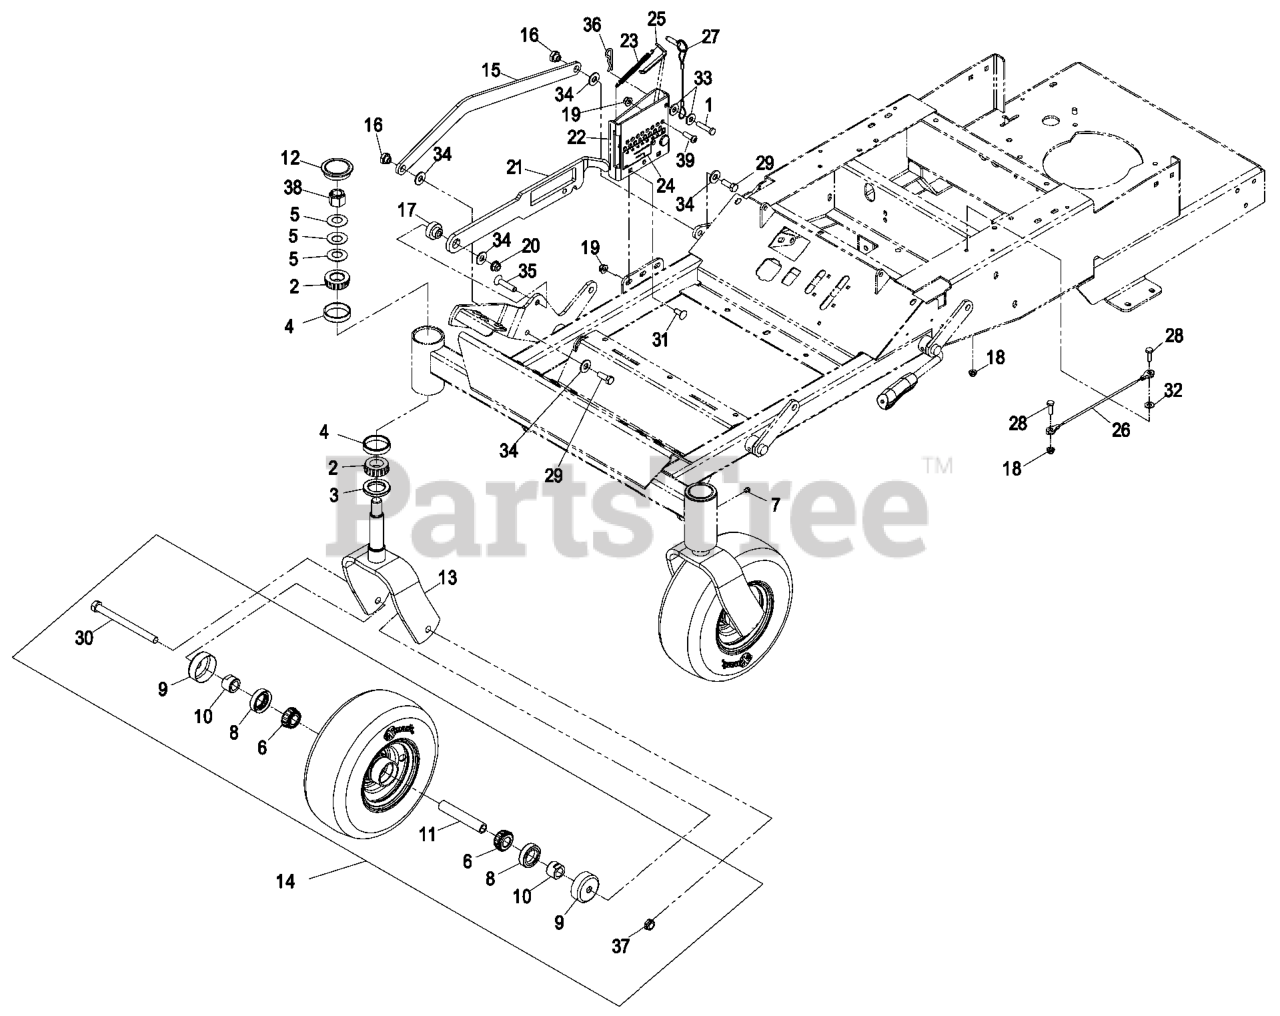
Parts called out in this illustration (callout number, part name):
1	PIN-CLEVIS
2	Cone-Bearing Tapered Roller
3	SEAL-GREASE
4	CUP-BEARING
5	WASHER-BELLVILLE
6	BEARING-CONE, TAPERED ROLLER
8	SEAL-CASTER
9	GUARD-SEAL
10	SPACER-NUT
12	CAP-GREASE
13	FORK-CASTER
14	WHEEL/TIRE AND BEARING AS
15	LINK-CONTROL, DECK
16	NUT-SHOULDER
17	BUSHING
19	NUT-HF, NI
20	NUT-HF, NI
21	PLATE,HEIGHT CONTROL
22	HEIGHT ADJUST ASM
23	SPRING-ADJUST, HEIGHT
24	DECAL-HEIGHT, DECK
25	PAWL-CONTROL, HEIGHT
26	CABLE-STOP, SEAT
27	HEIGHT PIN W/LANYARD ASM
28	SCREW-HH
29	SCREW-HH
30	SCREW-HH
31	SCREW-CARR
32	WASHER-PLAIN
33	WASHER-SPRING
35	SCREW-FH
36	PIN-COTTER
37	NUT-HEX
38	NUT-LOCK, NI
39	SCREW-HSBH
